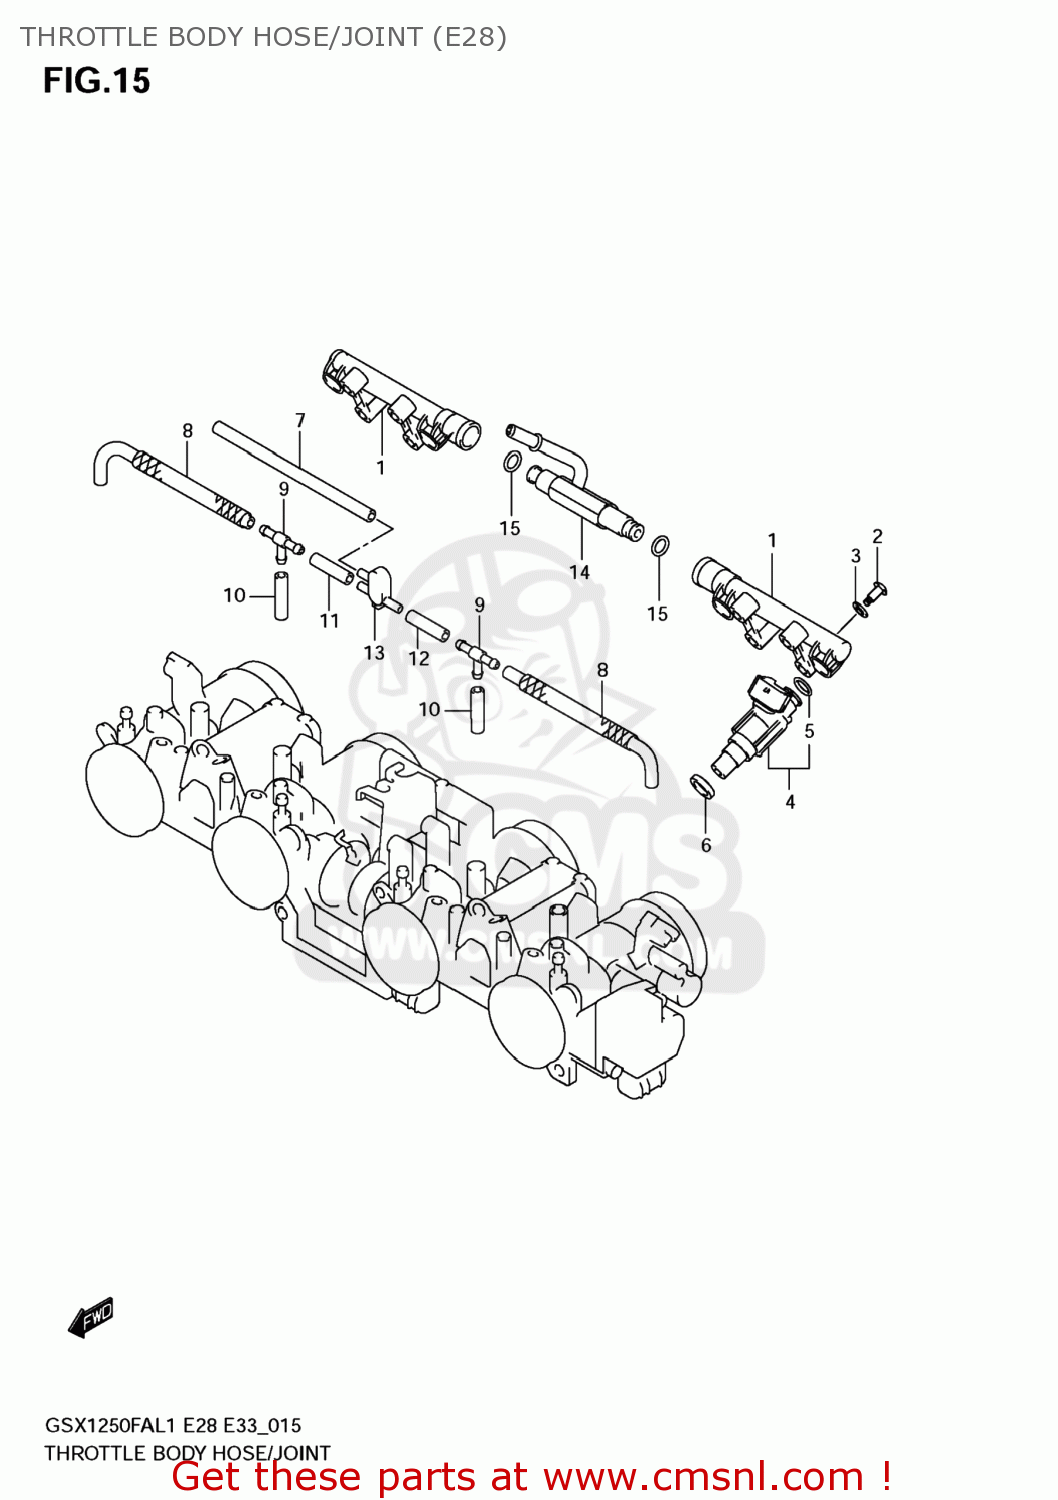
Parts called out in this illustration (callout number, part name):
1	DELIVERY PIPE
2	SCREW
3	PACKING (NAS)
4	INJECTOR ASSY
5	O-RING
6	SEAL
7	HOSE(L:425)
8	HOSE
9	3WAY,VACUUM HOSE
10	HOSE(L:425)
11	HOSE(L:425)
12	HOSE
13	JOINT
14	NIPPLE
15	O RING
